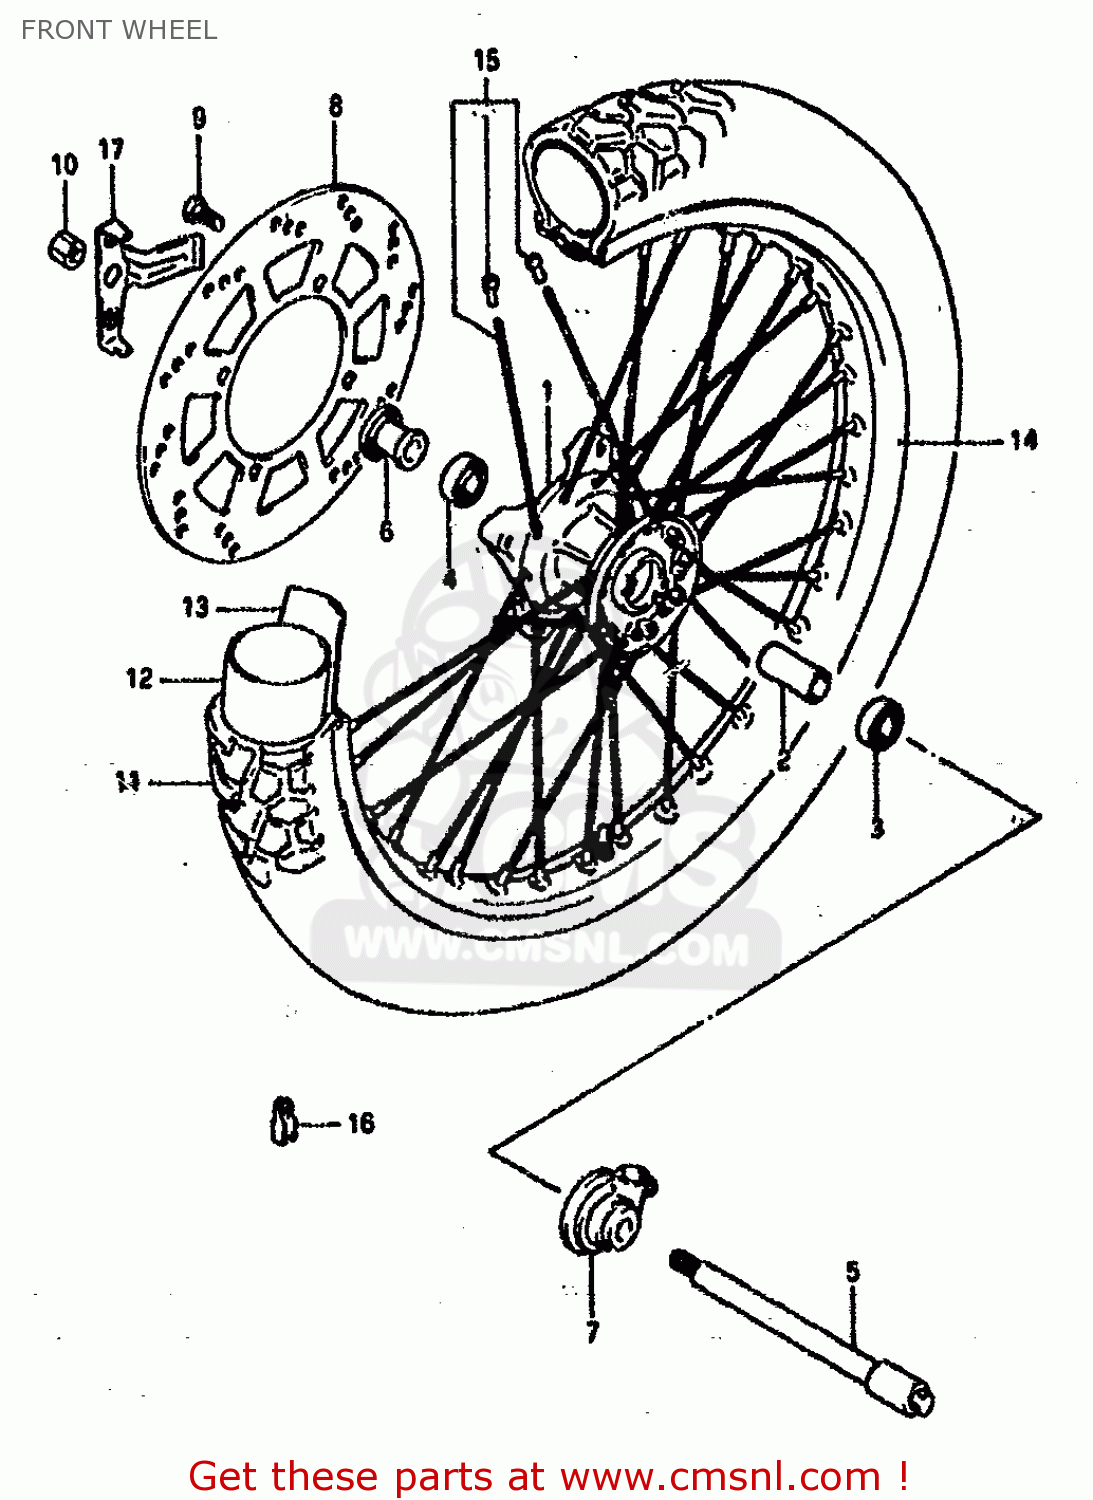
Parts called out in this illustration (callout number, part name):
1	HUB,FRONT WHEEL
2	SPACER,FR HUB BEARING
3	BEARING(15X32X15.9)
4	BEARING
5	AXLE,FR
6	SPACER,FRONT AXLE,LEFT
7	BOX ASSEMBLY,SPEEDOMETER GEAR
8	DISC,FR BRAKE
9	BOLT,BRAKE DISC
10	NUT
11	TIRE,FRONT (90/90-21 54S)
12	TUBE,INNER
13	PROTECTOR,WHEEL,INNER
14	RIM,FR WHEEL(21X1.85)
15	SPOKE SET,FR WHEEL
16	BALANCER,WHEEL
17	PLATE,PROTECTOR SET
